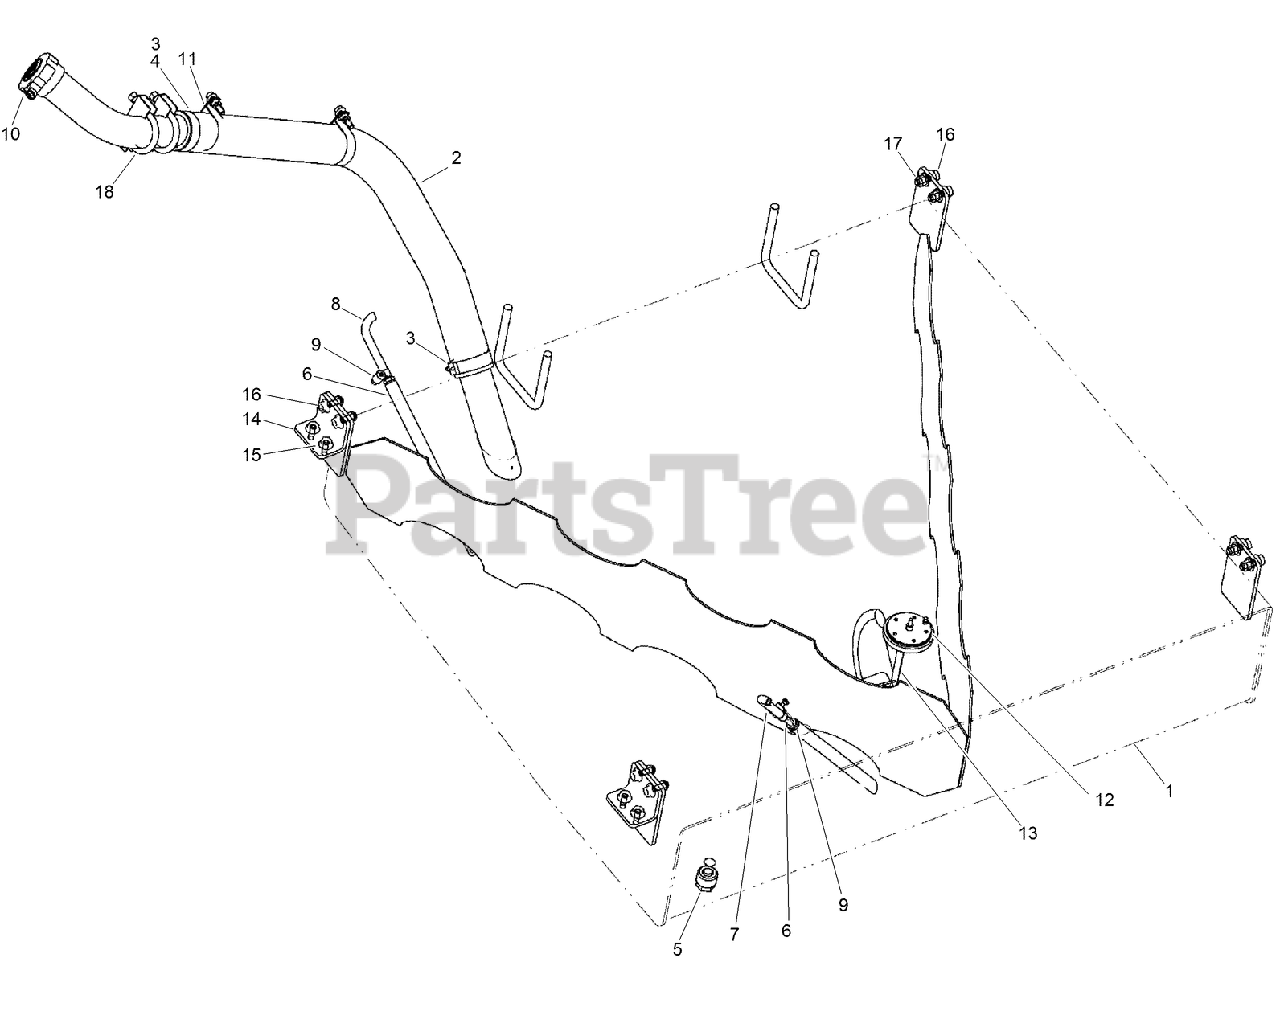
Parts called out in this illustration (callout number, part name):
1	WELDMENT - Fuel Tank
2	HOSE - Fuel Tank Fill
3	CLAMP, T-BOLT
4	NECK-FILLER, FUEL
5	PLUG-HEX, MAGNETIC
6	STEM-STRAIGHT, BEAD
7	HOSE - 3/8", Engine Fuel Supply
8	HOSE - 3/8?, Engine Fuel Return
9	CLAMP-HOSE
10	CAP-FUEL (W/LOCK)
11	CLAMP - Support, Hose
12	GASKET-SENDING UNIT
13	SENDER-FUEL
14	PLATE - Tank Mounting
15	SCREW, METRIC FLANGE w/BODY - M10 x 20
16	SCREW-HH
17	NUT-FLANGE, NYLOCK
18	BOLT-U, CLAMP
